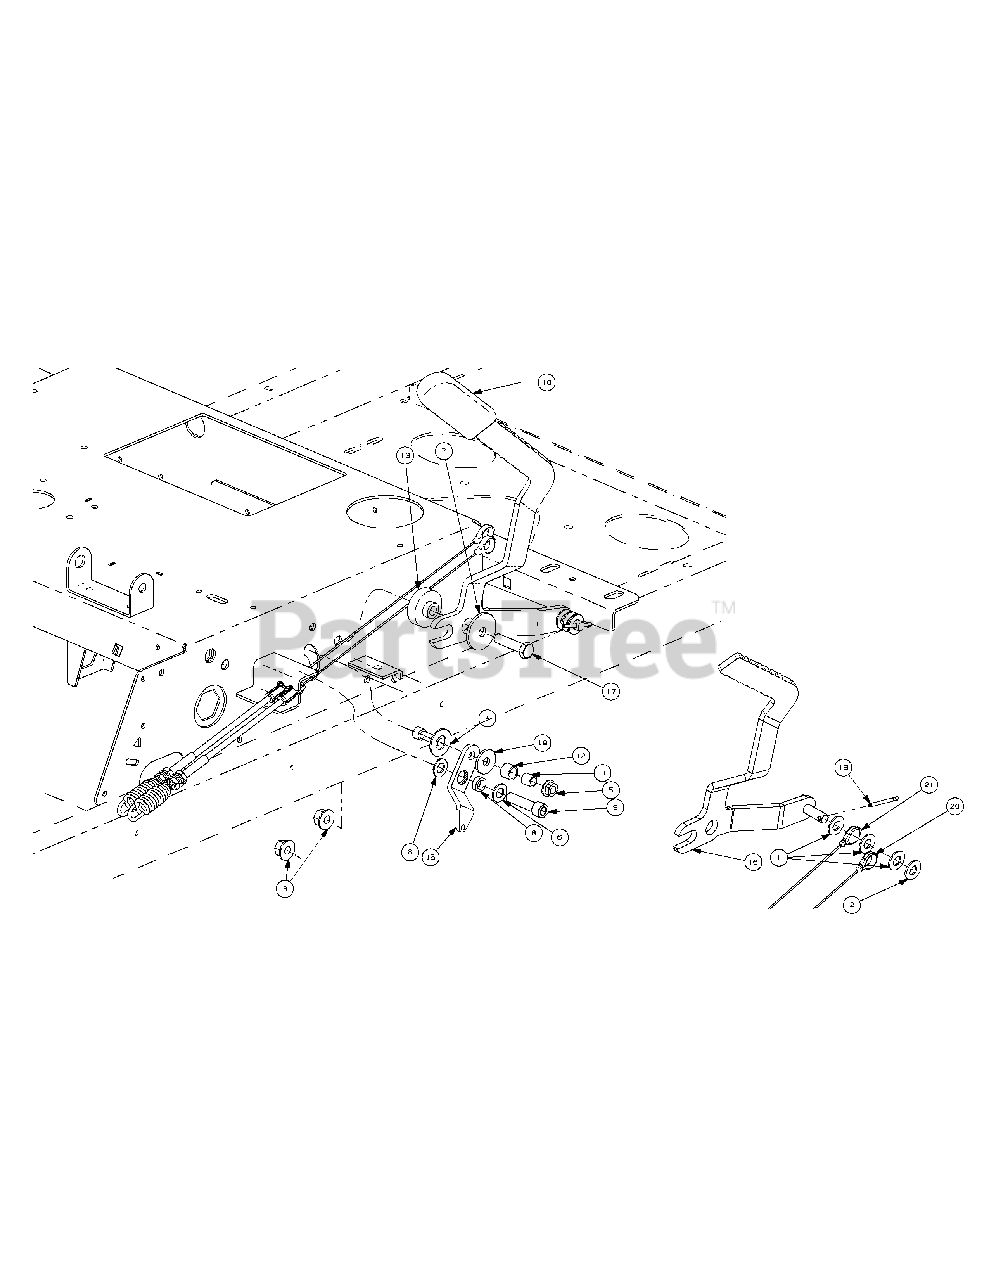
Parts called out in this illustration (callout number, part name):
1	Washer, .406 x 812 x .062
2	Hex Head Cap Screw, 5/16-18 x 1.00
3	Hex Nut, 3/8-16 Flange Lock
4	Slide Washer
5	Nut, 5/16-18, Flange Lock
6	Washer, .375 x .738 x .063
7	Flat Washer, .390 x 1.5 x .134
8	Spacer, .380 x .563 x .196
9	Sockethead Capscrew, 3/8-16 x 1.50
10	Parking Brake Grip
11	Spacer, .322 ID x .438 OD x .44
12	Spacer, .442 ID x .563 OD x .405
13	Step Hub, .379 x 1.5 x .257/.400
14	Sockethead Capscrew, 5/16-18 x 1.00
15	Lockout Lever Plate
16	Brake Handle
17	Hex Head Cap Screw, 3/8-16 x 1.50
18	Cotter Pin, 1/8 x 1.75
19	Washer, .345 x 1.00 x .100
20	Left Hand Brake Cable
21	Right Hand Brake Cable
